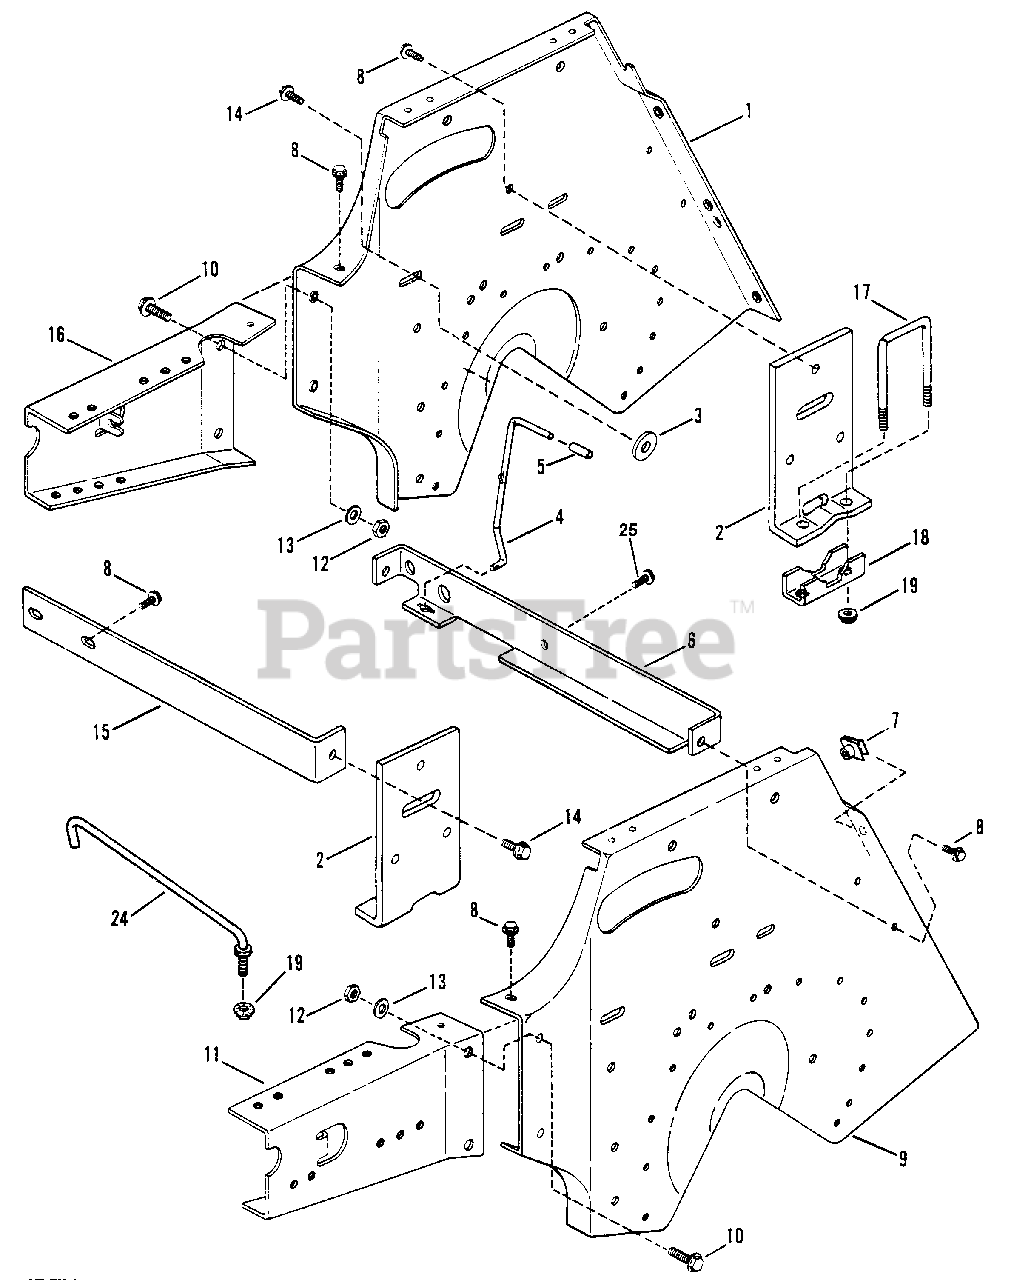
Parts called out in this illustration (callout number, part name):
1	TRANSMISSION SUPPORT, R.H. (No longer available)
2	BRACKET, Transmission Mount (No longer available)
4	ROD, Release
5	CAP, Release Rod
6	BRACE, Torque
7	NUT, 5/16 Push-On
8	SCREW, 5/16-18 x 5/8" Self-Tapping
9	TRANSMISSION SUPPORT, L.H. (No longer available)
10	BOLT, 3/8-16 x 1" Hex Flange Lock
11	EXTENSION, Transmission Support (Left Hand)(No longer available)
12	NUT, 318-16 Hex Center Lock
13	WASHER, 3/8" Flat
14	SCREW, 5/16-18 x 3/4" Self-Tapping
15	BRACE, Shift Bracket (No longer available)
16	EXTENSION, Transmission Support, R.H. (No longer available)
17	U-BOLT
18	SADDLE, U-Bolt
19	NUT, 5/16-18 Hex Flange Lock
24	SUPPORT, Footrest
25	TORX, ST Bolt 5/16" C x 7/8"
